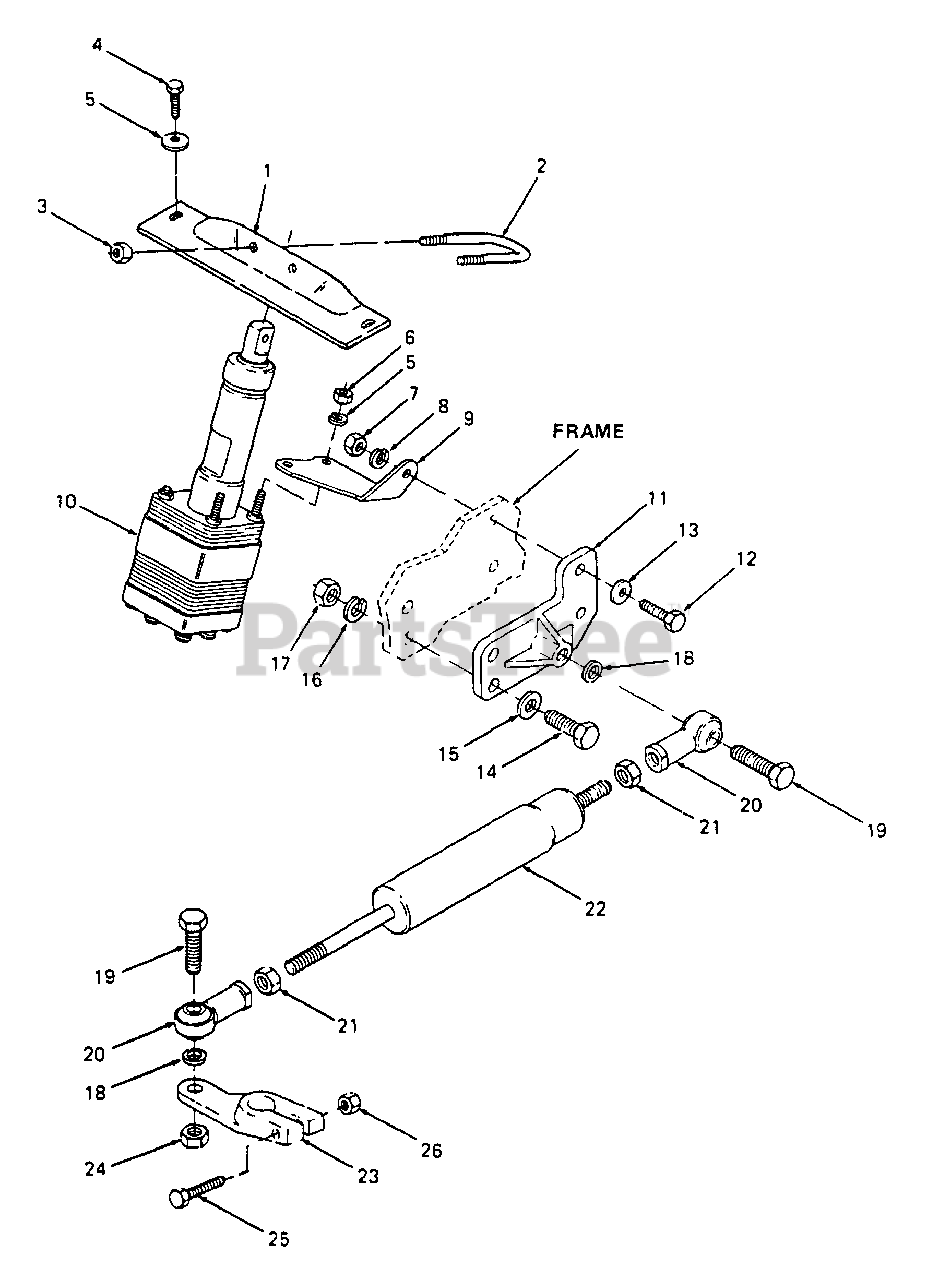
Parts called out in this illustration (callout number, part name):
1	Plate, Steering Support
3	Nut, Hex Center Lock, 5/16-24
4	Screw, Hex Cutting, 5/16-18 x .75 Lg
5	Washer, Bell, .345 x .88 x .060 Thk
6	Nut, Hex, 5/16-24 GR5
7	Nut, Hex Center Lock, 3/8-16 GR5
8	Washer, Lock, 3/8
9	Bracket, Power Steering Box Mtg
10	Power Steering Box w/Flat
13	Washer, Flat, .385 x .87 x .06 Thk HDN
14	Screw, Hex Cap, 1/2-13 x 1.25 Lg GR5
15	Washer, Flat, .51 x 1.12 x .06 Thk HDN
16	Washer, Lock, 1/2
17	Nut, Hex Center Lock, 1/2-13 GR5
18	Washer, Flat, .531 x .688 x .054 Thk
19	Screw, Hex Cap, 1/2-20 x 1.5 Lg GR5
20	Alignaball End, 1/2-20
21	Nut, Hex Jam, 1/2-20 GR5
24	Nut, Hex, 1/2-20 GR5
25	Screw, Hex Cap, 5/16-18 x 1.38 Lg GR5
26	Nut, Hex Center Lock, 5/16-18 GR5
